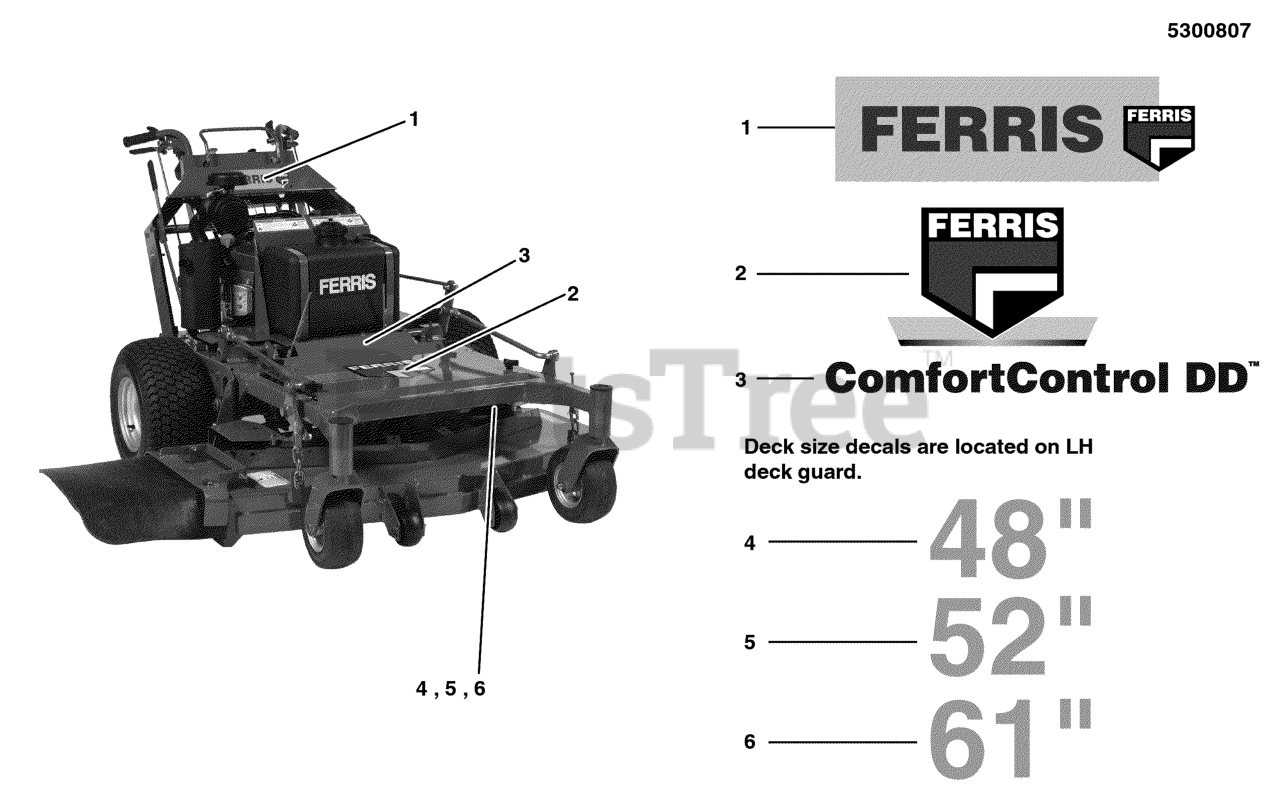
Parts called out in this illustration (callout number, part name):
1	DECAL, FERRIS TEXT & LOGO
2	DECAL, FERRIS BADGE
3	DECAL, COMFORT CONTROL
4	DECAL, 48
5	DECAL, 52
6	DECAL, 61"
